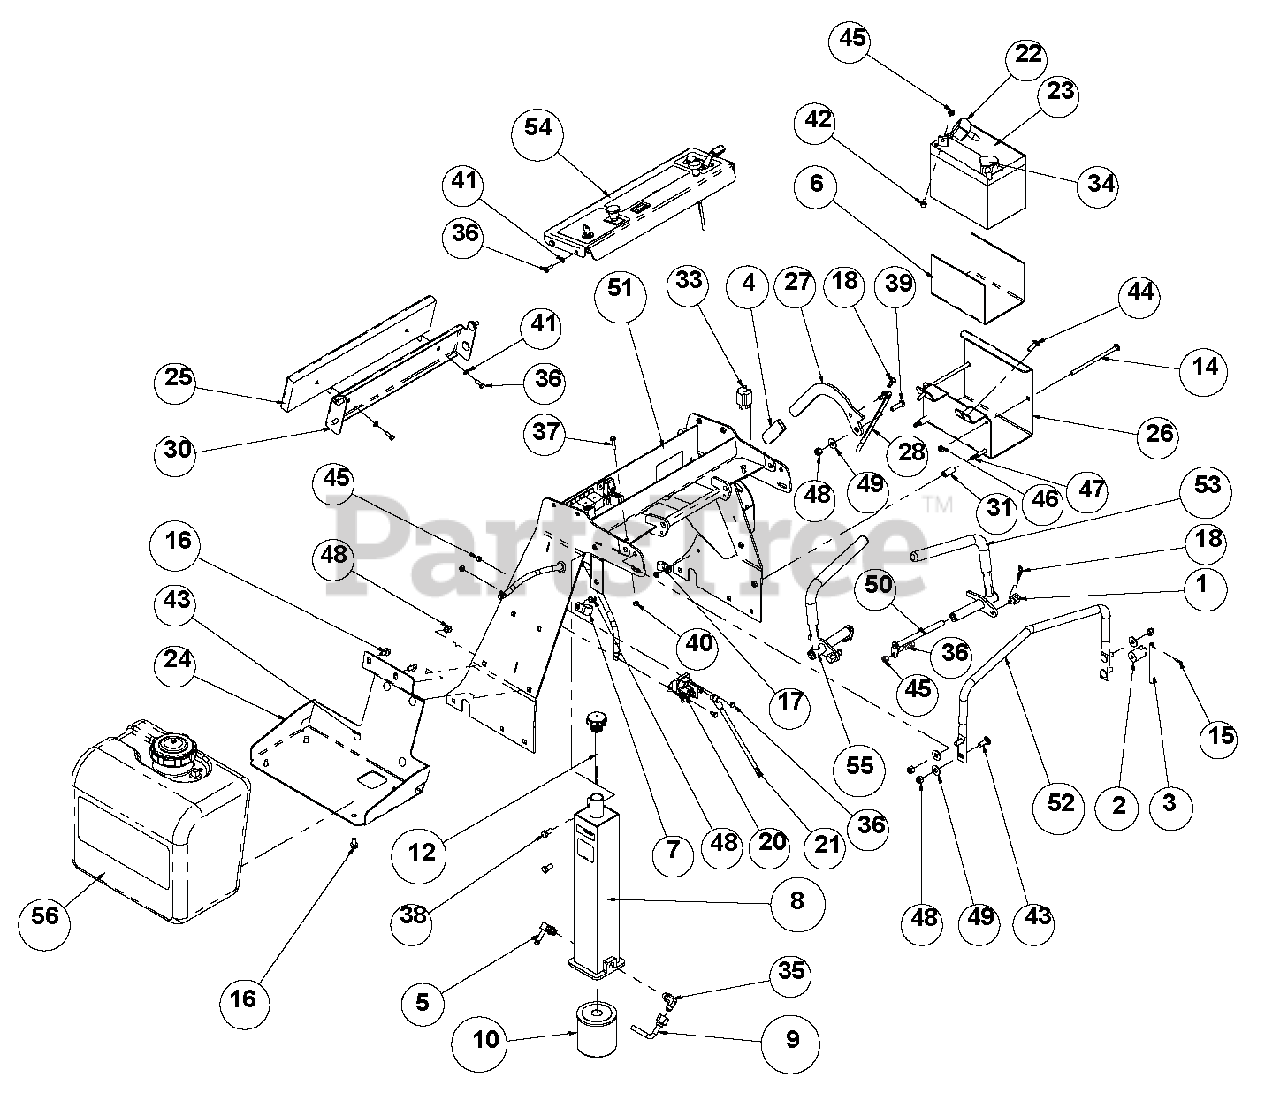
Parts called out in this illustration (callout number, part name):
1	SWIVEL
2	BASE, SPEED CONTROL LOCK
4	GRIP
5	FTG-ADPTR .562-18 ST THD
6	ISOLATOR PAD, BATTERY
7	P-CLIP, .750 INSULATED
8	HYDRAULIC RESERVOIR, INC DECAL
9	ELBOW FITTING
10	ELEMENT, OIL FILTER
11	CLAMP
12	CAP
13	HOSE, 1/4" ID LOW PERM FUEL 50
14	BOLT, 3/8-16 X 3-3/4 CHCS
15	PIN, SPRING 5/32 X 1
16	SCREW,HEX,FL,JDS123,M8X1.25X16
17	P-CLIP, .500 INSULATED
18	PIN-HAIR INT .09X1.65 PL
19	GROMMET, ROUND RUBBER .625X.19
20	SOLENOID
21	STARTER CABLE
22	CABLE, BATTERY STARTER 48"
23	BATTERY, 12V-U1-CCA270MIN
24	BRACKET, FUEL TANK MOUNTING
25	PAD, THIGH
26	TRAY, BATTERY
27	LEVER, BRAKE
28	LINK, BRAKE Y
29	BUSHING, BRAKE PIVOT Y
30	PAD, THIGH
31	BUSHING, .364X.540X1.250 Y
32	HARNESS, WIRING
33	SWITCH, NO-NO-NC GREY PLUNGER
34	CABLE, BATTERY GROUND - 20.5"
35	ADPT 2503-6-6
36	BOLT, 1/4-20X.750 HEX 5 Y
37	BOLT, 1/4-20X1.00 HEX 5 Y
38	BOLT, 3/8-16X.750 HEX 5 Y
39	BOLT, 3/8-16X1.25 HEX 5 Y
40	QUICK START SHEET
41	WDMT,IDLER PIVOT RAPID XZ 52"
42	PLATE, ENGINE MOUNT
43	BOLT, 3/8-16X1.00 CRG 5 SN Y
44	BOLT, 5/16-18X1.00 CRG 2 Y
45	LOCKNUT, 1/4-20 WHIZ Y
46	LOCKNUT, 5/16-18 NYLOC Y
47	BOLT, 5/16-18X2.00 CRG 5 Y
48	LOCKNUT, 3/8-16 NYLOC Y
49	WASHER, .375 REG FLAT Y
50	WLDT, PIN AND LOCK Y
51	WLDT, ARIENS CONSOLE W/DECALS
52	SUPPORT, HANDLE PAINTED
53	LH CONTROL LEVER W/GRIP
54	ASSEMBLY, CONSOLE ARIENS
55	RH CONTROL LEVER W/GRIP
56	TANK-FUEL 48P/S W/CAP W/O LOGO
